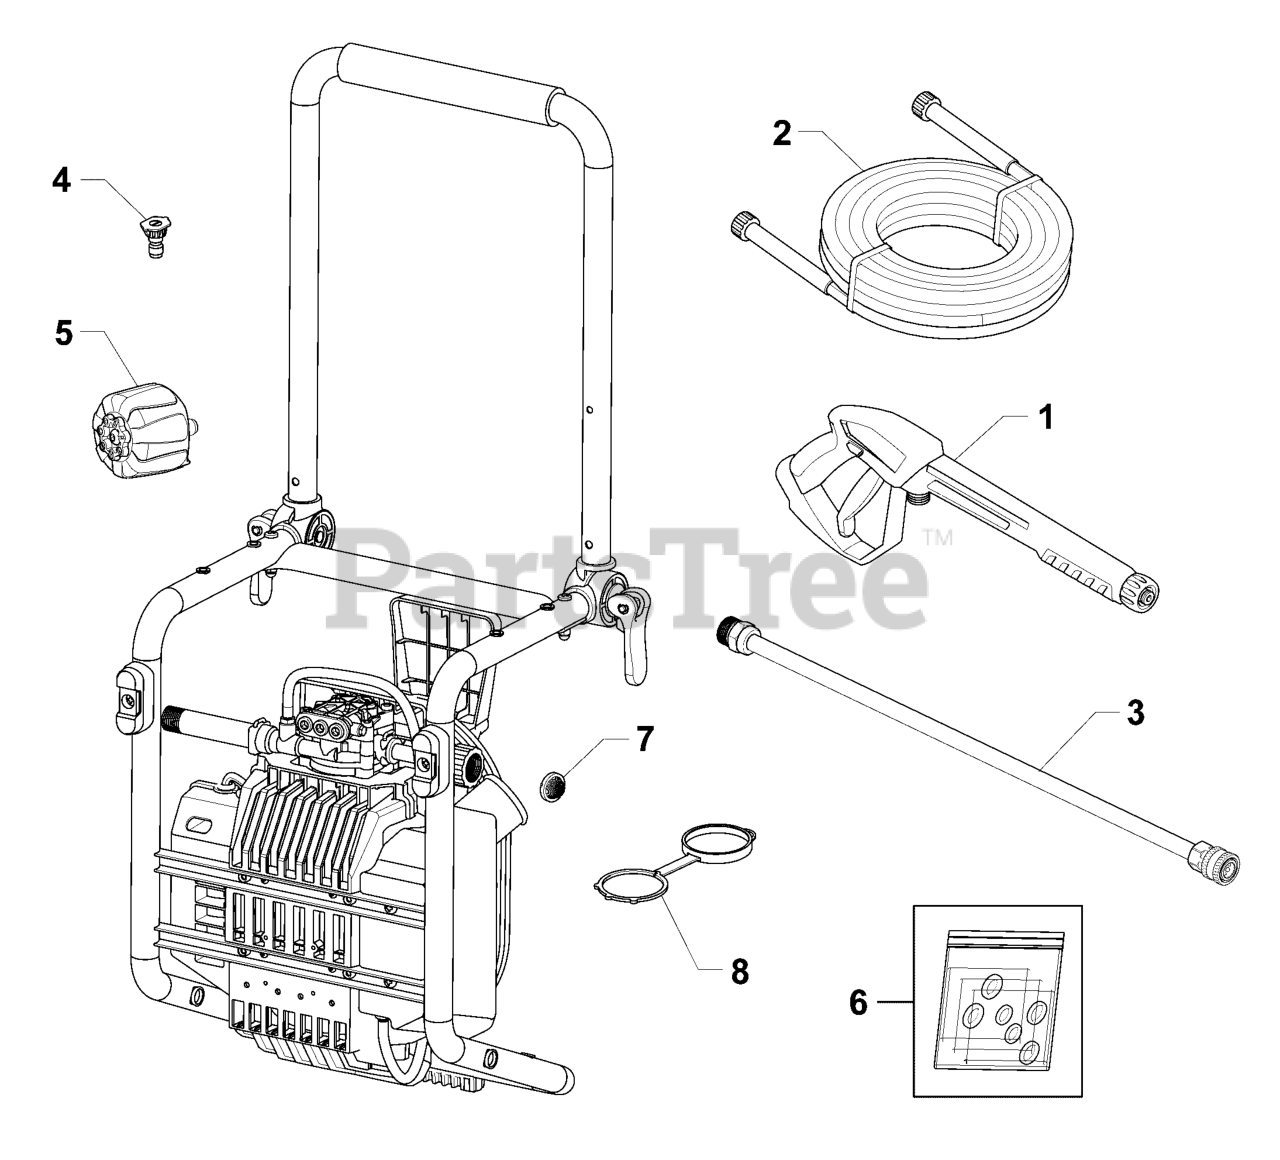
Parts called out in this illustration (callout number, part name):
3	EXTENSION, QC
6	KIT-O-RING MAINTENANCE
7	FILTER-GARDEN HOSE
